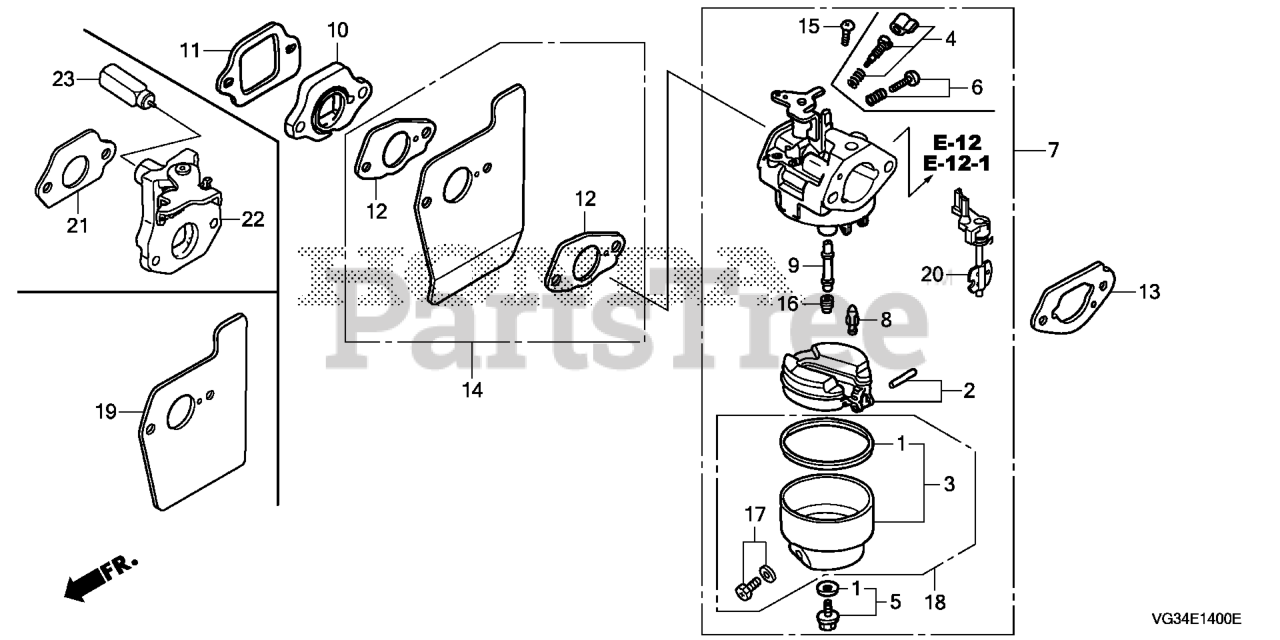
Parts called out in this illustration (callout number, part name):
1	GASKET SET
2	FLOAT SET
3	CHAMBER SET, FLOAT (CARBURETOR NO.)
5	SCREW SET B
5	SCREW SET
7	CARBURETOR ASSY. (BB76A A)
7	CARBURETOR ASSY.
8	VALVE, FLOAT (Honda Code 7934714). (CARBURETOR NO.)
9	NOZZLE, MAIN
15	SCREW, PAN (5X6)
16	JET, MAIN (#60) (Honda Code 0635474). (CARBURETOR NO.)
16	JET, MAIN (#62) (Honda Code 0635482). (CARBURETOR NO.)
16	JET, MAIN (#55) Use up to Engine SN BB28A D.
16	JET, MAIN (#58) Use up to Engine SN BB28A D.
19	GUIDE, AIR
20	CHOKE SET
21	GASKET, INSULATOR
22	CONTROL ASSY., CHOKE
23	THERMO WAX ASSY.
